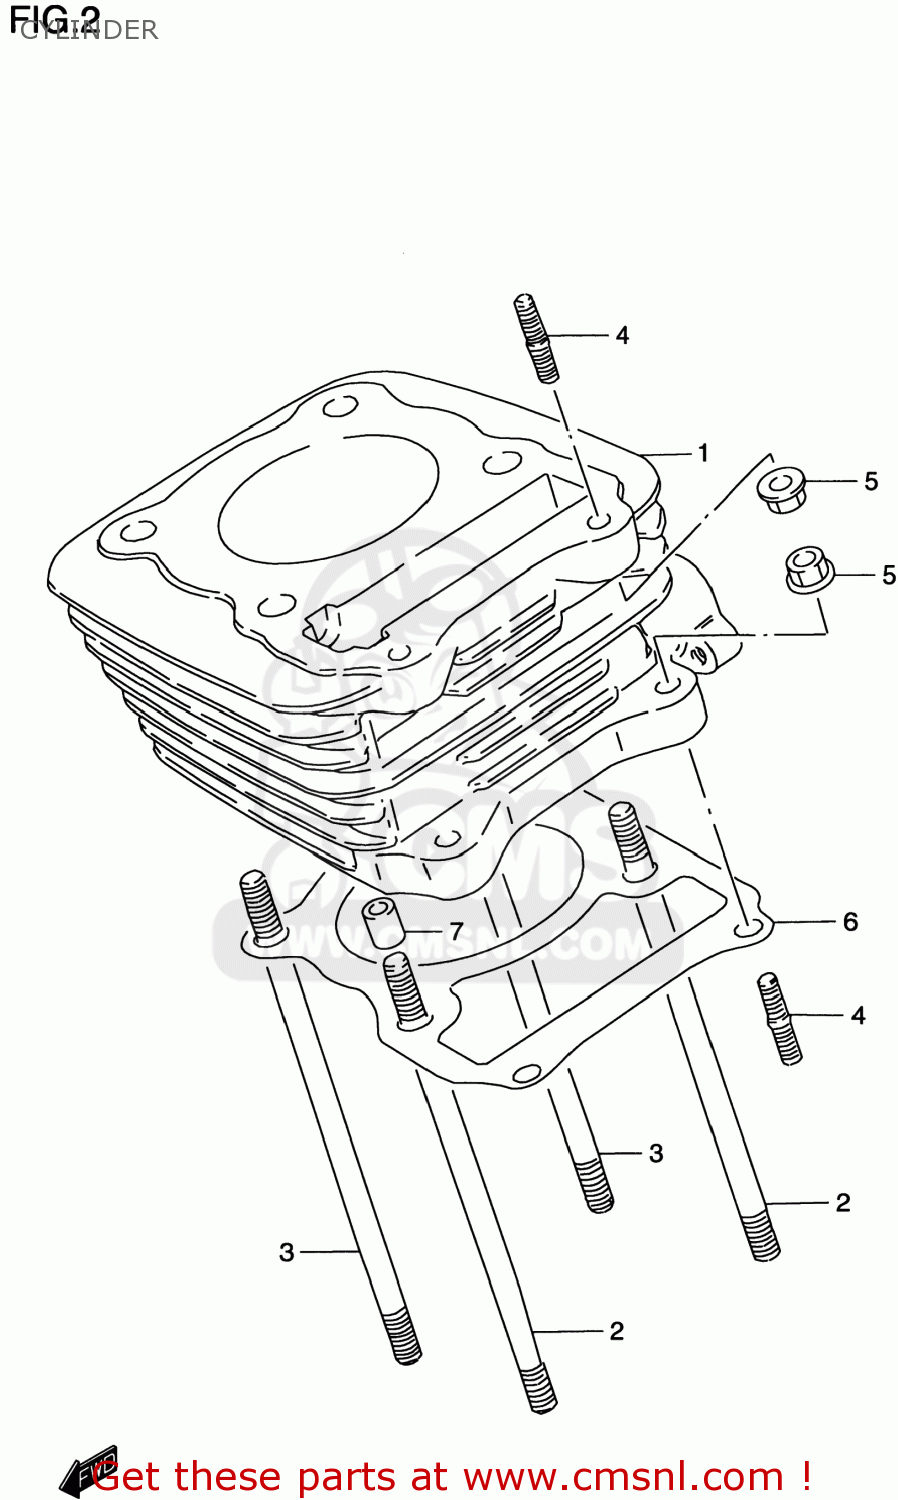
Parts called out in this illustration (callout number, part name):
1	CYLINDER COMP
2	BOLT,STUD
3	BOLT,STUD(8X167)
4	STUD BOLT
5	NUT
6	GASKET,CYLINDER (NAS)
7	PIN
